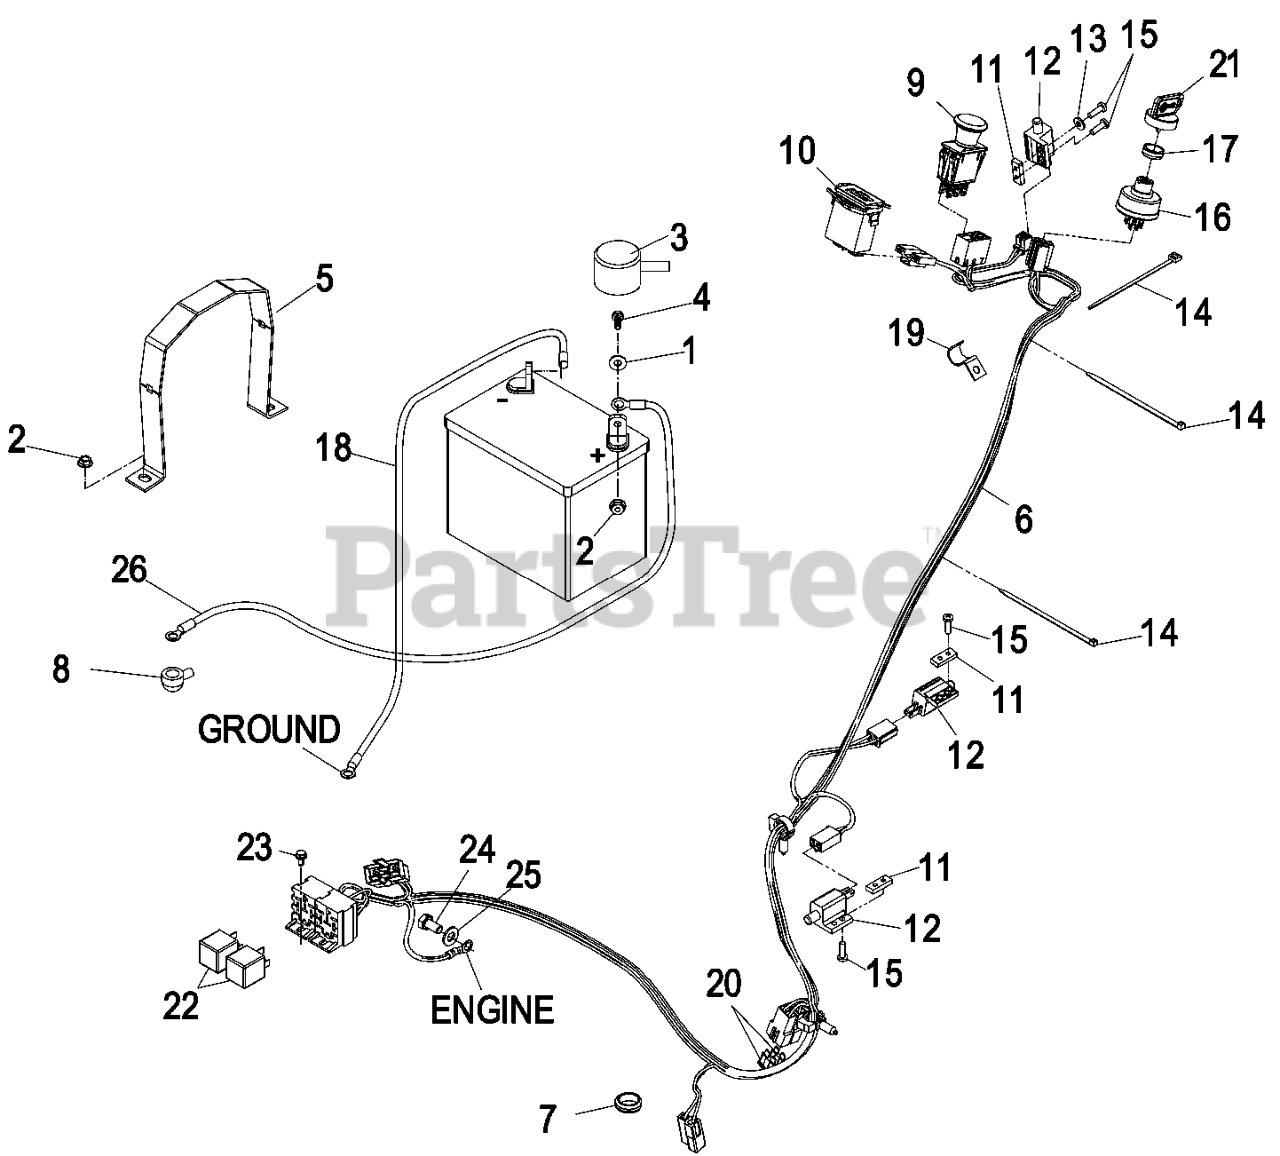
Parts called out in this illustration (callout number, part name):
1	WASHER-FLAT
3	INSULATOR-BATTERY
4	SCREW-HH
5	STRAP,BATTERY HOLDDOWN
6	HARNESS,TTH ECS WIRING
7	GROMMET
8	INSULATOR-SOLENOID
9	SWITCH-PTO
10	METER-HOUR
11	PLATE-TAPPED
12	SWITCH-OPEN, NORMALLY
13	WASHER-FLAT
14	TIE-PLASTIC
15	SCREW-PPH
17	NUT-SWITCH, IGNITION
18	WIRE-GROUND
19	CLIP-HALF, LOOM
20	FUSE-BLADE TYPE, 20 AMP
21	KEY-IGNITION
23	SCREW-HWH
24	SCREW-HH
25	WASHER-PLAIN
26	POSITIVE BATTERY CABLE AS
